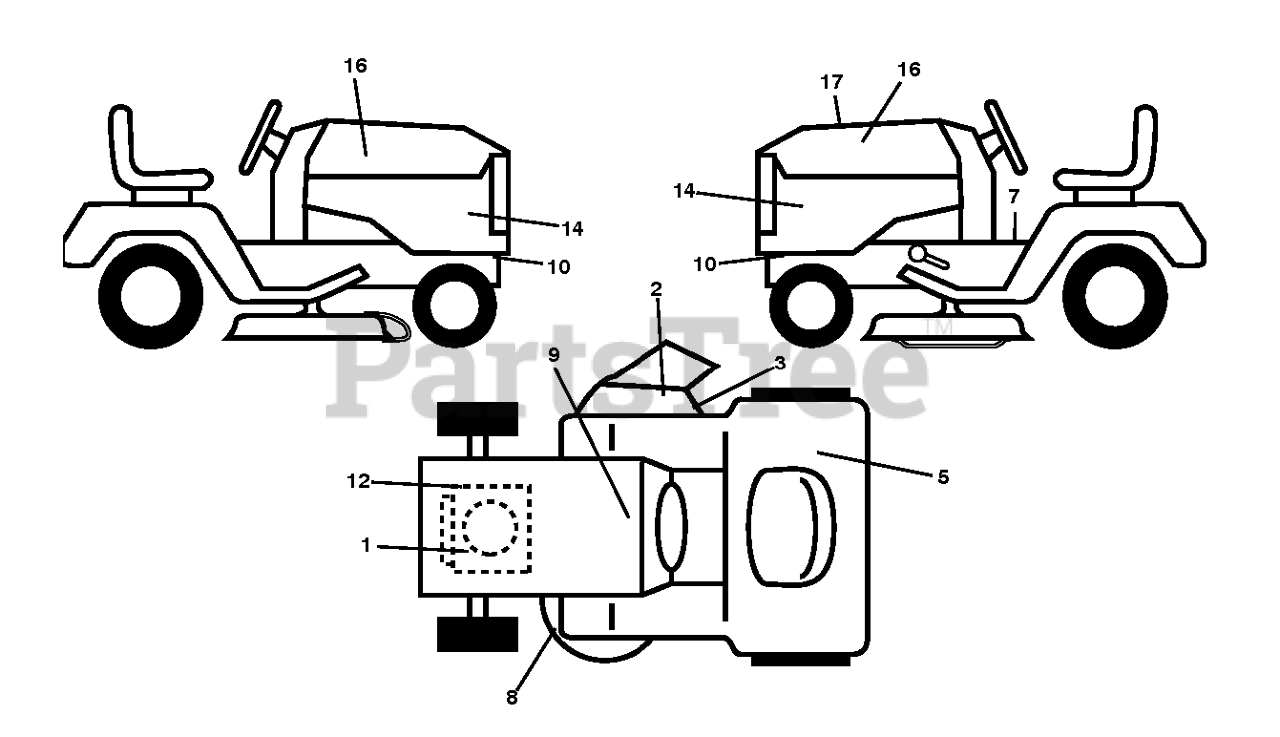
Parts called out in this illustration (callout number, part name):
1	DECAL DECAL.ENG.BS.ENDUR.22HP.
2	DECAL, DECK DEFLECTOR, WARNING
3	DECAL.DFLCTR.WARNNG.CTFNGR.SYM
5	DECAL CERTIFICATION DECAL EMCC
7	DECAL.TRAC.FNDR.GLBLWRNG.RDYST
8	DECAL.V-BELT.SCH.42/46"MEC/ELE
9	DECAL BTRY SYMBOLS
10	DECAL.CHASSIS.HOT.MUFFLER
12	DECAL.ENGINE.WARNING
14	DECAL.SDPNL.HUSQGT.TS246.RH/LH
16	DECAL.BADGE.170MM.TEXTLOGO.
17	DECAL.RPL.BSM44.END.TLW.K57
